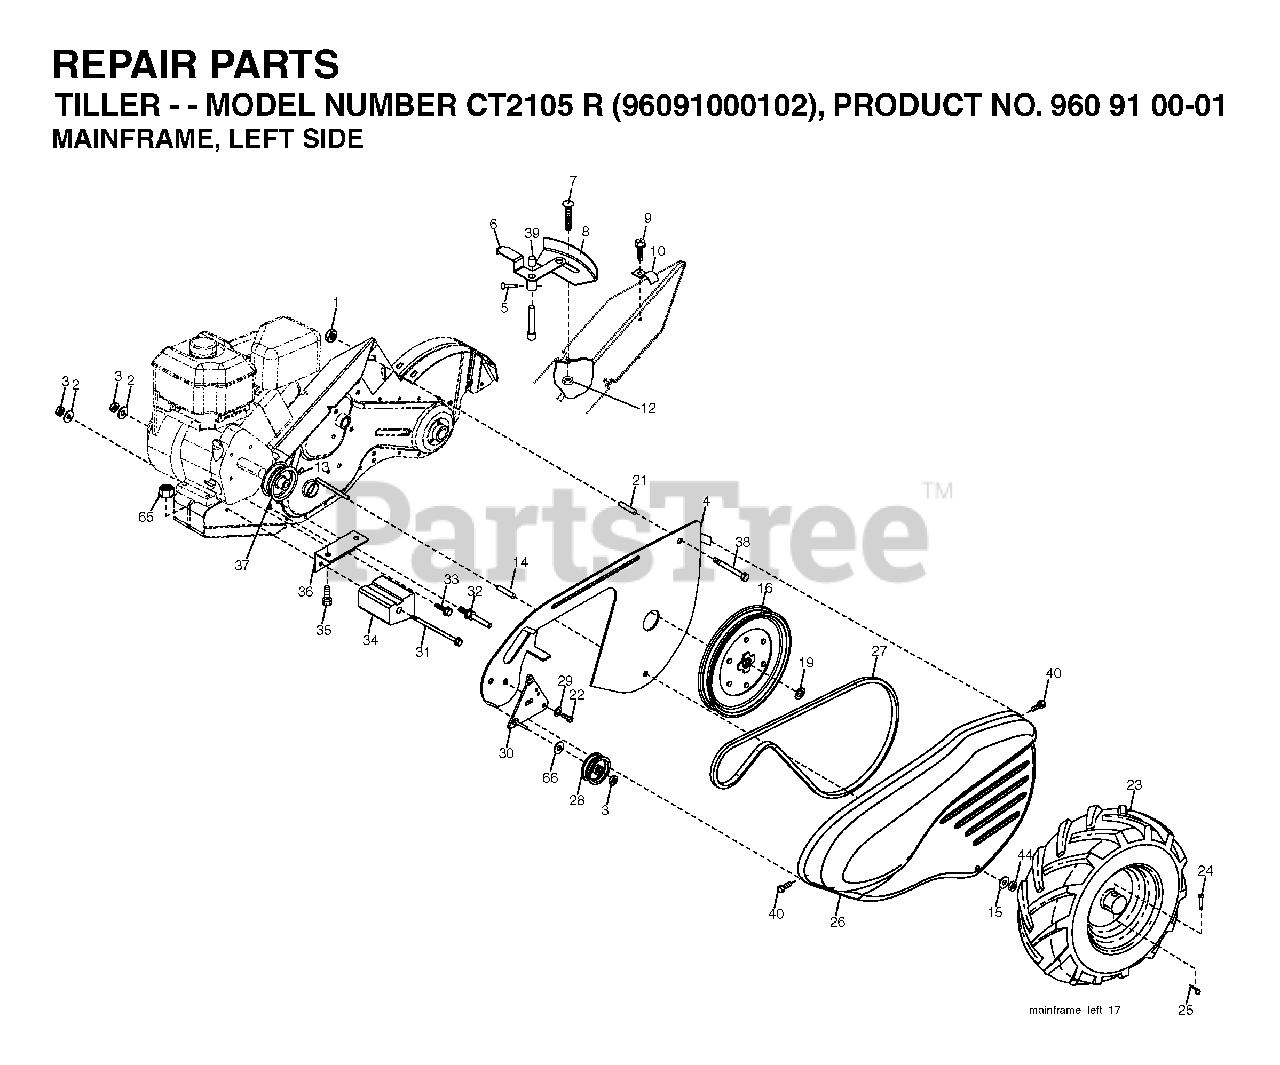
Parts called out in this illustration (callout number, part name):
1	NUT
2	WASHER, LOCK 3/8
3	NUT.HEX.3/8-16UNC
5	PIN.SPIROL.FLARED
6	LEVER ASM CRT
9	TAPPING SCREW
10	CONDUIT CLIP T
12	NUT
13	SET SCREW **
14	SPACER-SPLIT.327 X .42
15	WASHER
16	SHEAVE, TRANSMISSION
19	RETAINING RING LT
21	SPACER CRT
24	RIVET,DRILLED
25	RETAINER M
27	V-BELT
28	PULLEY-IDLER TI
29	KLIP RING
30	BRACKET.ASM.IDLER
31	BOLT.FIN.HEX.3/8-16UNC
32	SHIFT ARM CRT
33	BOLT
34	COUNTERWEIGHT.LH.CRT
35	BOLT, HEX 5/16-18X1-3/4
36	BRACKET LH CRT
37	ENGINE PULLEY
38	BOLT
39	CAP.PLUNGER.BLACK
40	SCREW.HEX.WSH.SLT.#10-24X.50
44	NUT.71038.31-18.HEX.NYLOCK
65	LOCKNUT-FLANGE 5/16-18
66	WASHER
5321243-66	RIM
5321247-18	VALVE STEM LT
